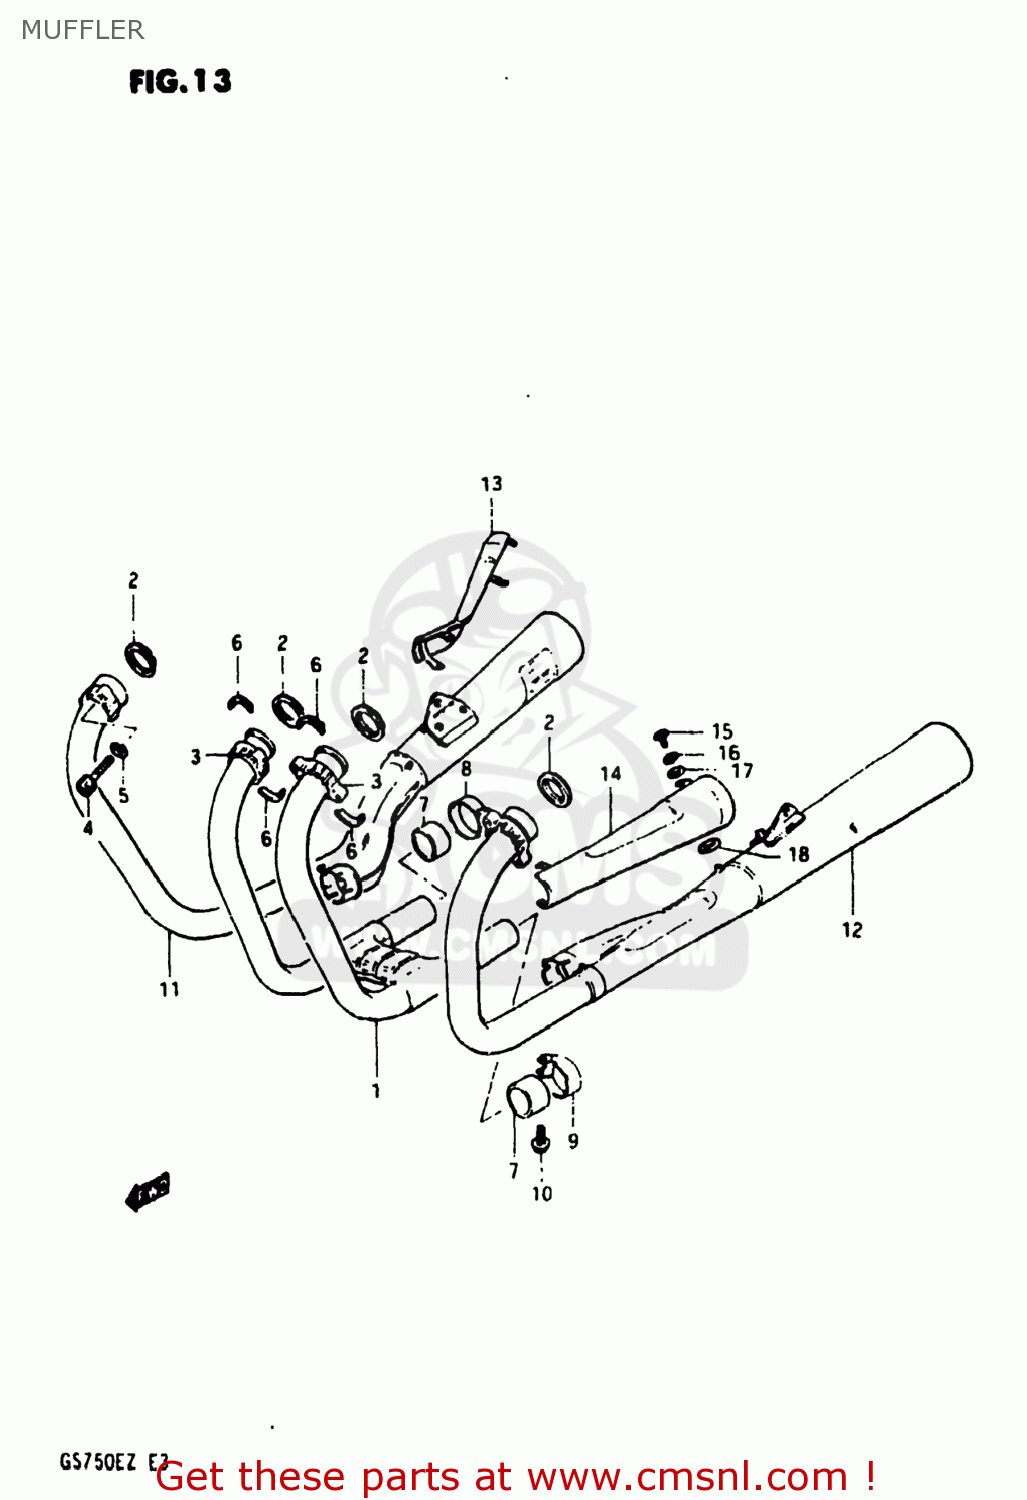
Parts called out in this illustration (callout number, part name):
1	PIPE,EXHAUST
2	GASKET,EXHAUST PIPE (NAS)
3	CLAMP,EXHAUST PIPE
4	BOLT
5	LOCK WASHER
6	PLATE,EXHAUST
7	CONNECTOR,MUFFLER
8	CLAMP,MUFFLER CONNECTOR,R
9	CLAMP,MUFFLER CONNECTOR,L
10	BOLT
11	MUFFLER ASSEMBLY
12	MUFFLER ASSEMBLY
13	COVER,MUFFLER
14	COVER,MUFFLER
15	SCREW
16	LOCK WASHER
17	WASHER
18	GASKET 6.2X12X1.5 (MCA)
